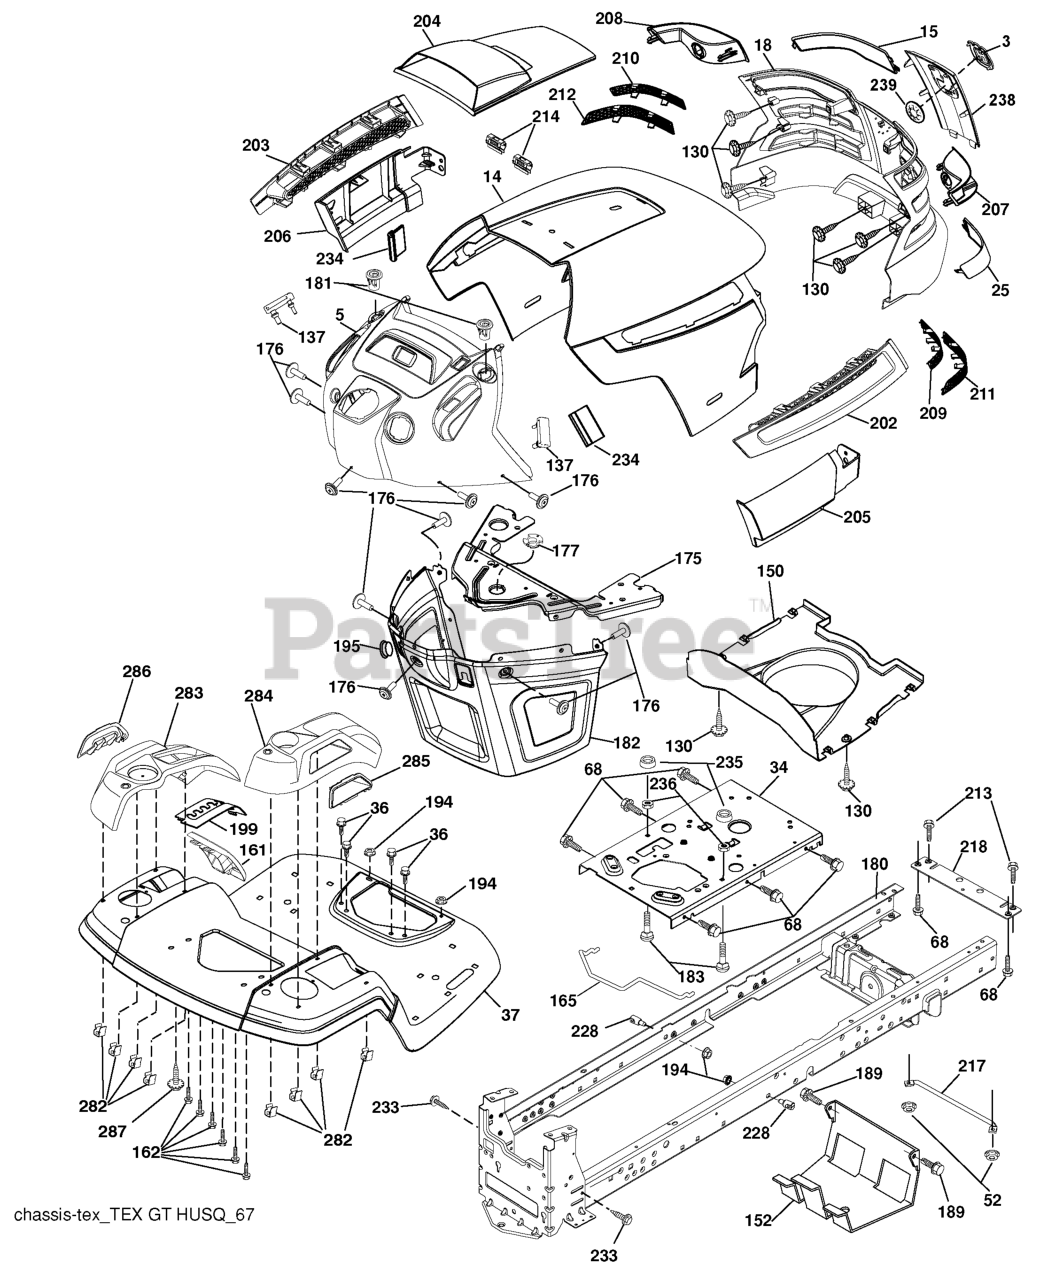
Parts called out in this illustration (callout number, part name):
3	RP LOGO
5	DASH.ASM.HUSQ.GT
14	HOOD
15	LENS.LH.TEX.GT.HUSQ.CL
18	GRILL.ASM.HUSQ.TG/CRD.W/TRIM
25	LENS.RH.TEX.GT.HUSQ.CL
34	PLATE.ENGINE.WELDED.CHASSIS
36	SCREW 5/16"
37	FENDER.TLT.FS.W/CPH/FW/RSF.ORN
52	LOCKNUT
68	Screw 5/16-18 x 1/2
130	SCREW.#10 X 0.750.BOS
137	BUMPER DASH
150	AIR.DUCT.HOOD.TEX.GT.HUSQ
152	SHIELD.BROWNING.W/TEX
161	WINDOW FUEL
162	SCREW.HI-LO.CONSOLE
165	SUPPORT.TANK.REAR.W/TEX
175	PLATE.CROSSMEMBER.HUSQ
176	SCREW.#10-24X5/8.RN.QU
177	BUSHING, STEERING
180	CHASSIS
181	BUSHING.MNT.FEND.CRGO.
182	DASH.LOWER.COMMON.12V.ADAPTOR
183	BOLT.5/16-18X1-1/4 FULL.THREAD
189	SCREW
194	NUT LOCK HEX FLANGE 5/16-18
195	PLUG.HOLE.DASH.LOWER.12V.BLK
199	PLATE.DECK.LIFT.HUSQ.LT
202	VENT.SIDE.HOOD.HUSQ.RH.GREY
203	VENT.SIDE.HOOD.HUSQ.LH.GRAY
204	HOOD VENT
205	SKIRT.HOOD.SIDE.HUSQ.RH.GREY
206	SKIRT.HOOD.SIDE.HUSQ.LH.GREY
207	BEZEL.RH.TEX.GT.HUSQ
208	BEZEL.LH.TEX.GT.HUSQ
209	INSERT.HEX.GRILL.HUSQ.GREY
210	INSERT.HEX.GRILL.HUSQ.
211	INSERT.HEX.GRILL.HUSQ.
212	INSERT.HEX.GRILL.HUSQ.
213	BOLT
214	CLIP.RETAINER.TINNER.
217	ROD.PIVOT.HOOD
218	X-PIECE.HOOD.STOP.NON/
228	STUD.FASTNER.W/ANTI-ROTATE
233	BOLT.SHOULDER
234	BUMPER.HOOD.TEX.HUSQVARNA
235	SPACER FENDER
236	NUT.CENTERLOCK.5/16-
238	TRIM.HUSQ.TG/CRD.SERVICE
239	NUT PUSH M
282	CLIP.RETAINER.CONSOLE.LT.HUSQ
283	RP CONSOLE ASM.DECKLFT.RSF.
284	RP CONSOLE ASM.PDL CNTRL.HUSQ
285	CONSOLE INSERT RH
286	CONSOLE.INSRT.LH.HUSQ.LT.BLACK
287	SCREW 1/4X20
